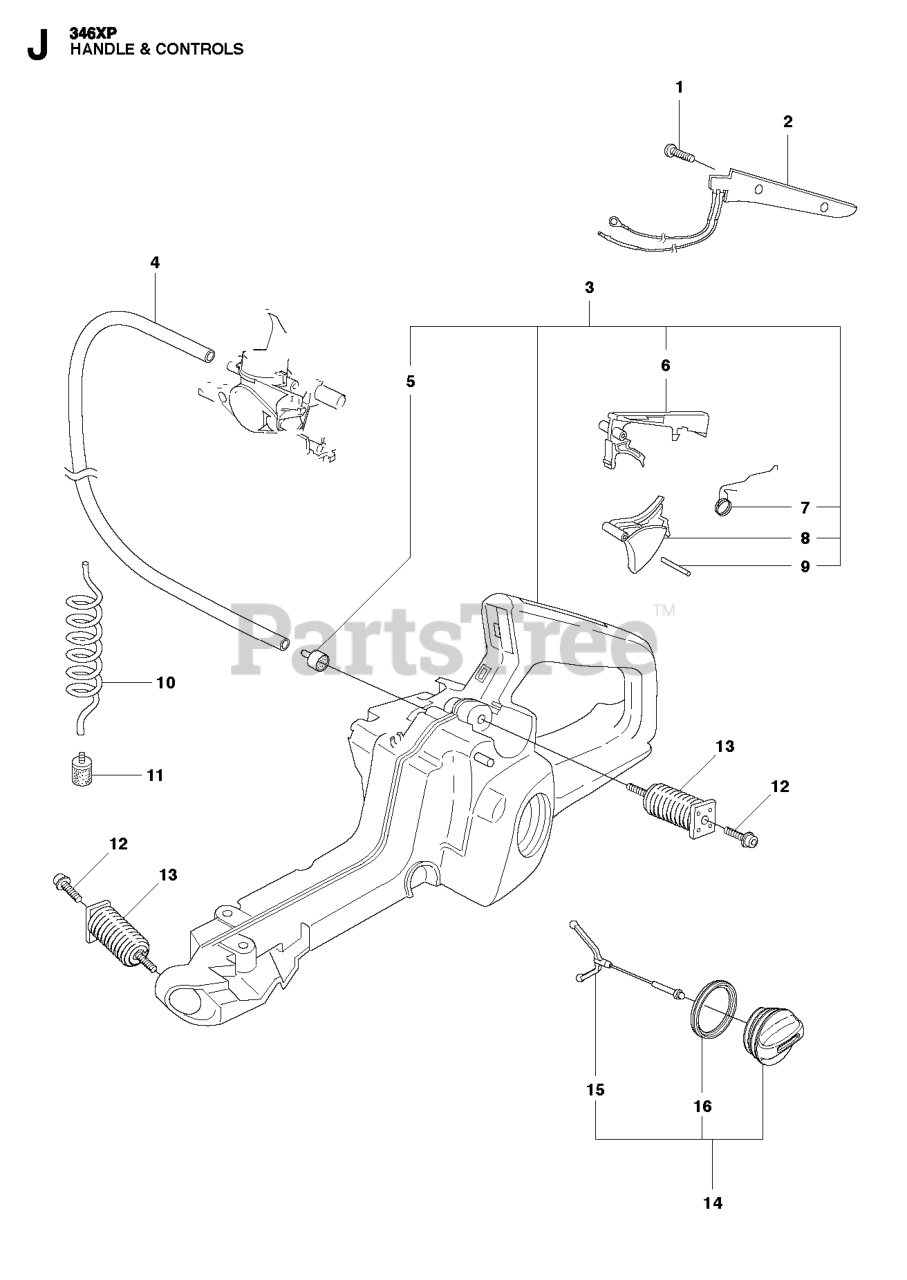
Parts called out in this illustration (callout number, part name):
1	SCREW
2	HANDLE CIRCUIT
4	FUEL HOSE
5	VALVE PLUG
5	FILTER PLUG
5	FUEL TANK VENT
6	THROTTLE LOCK
10	FUEL HOSE
11	RP FUEL FILTER
13	VIBRATION ABSORBER
14	TANK CAP
